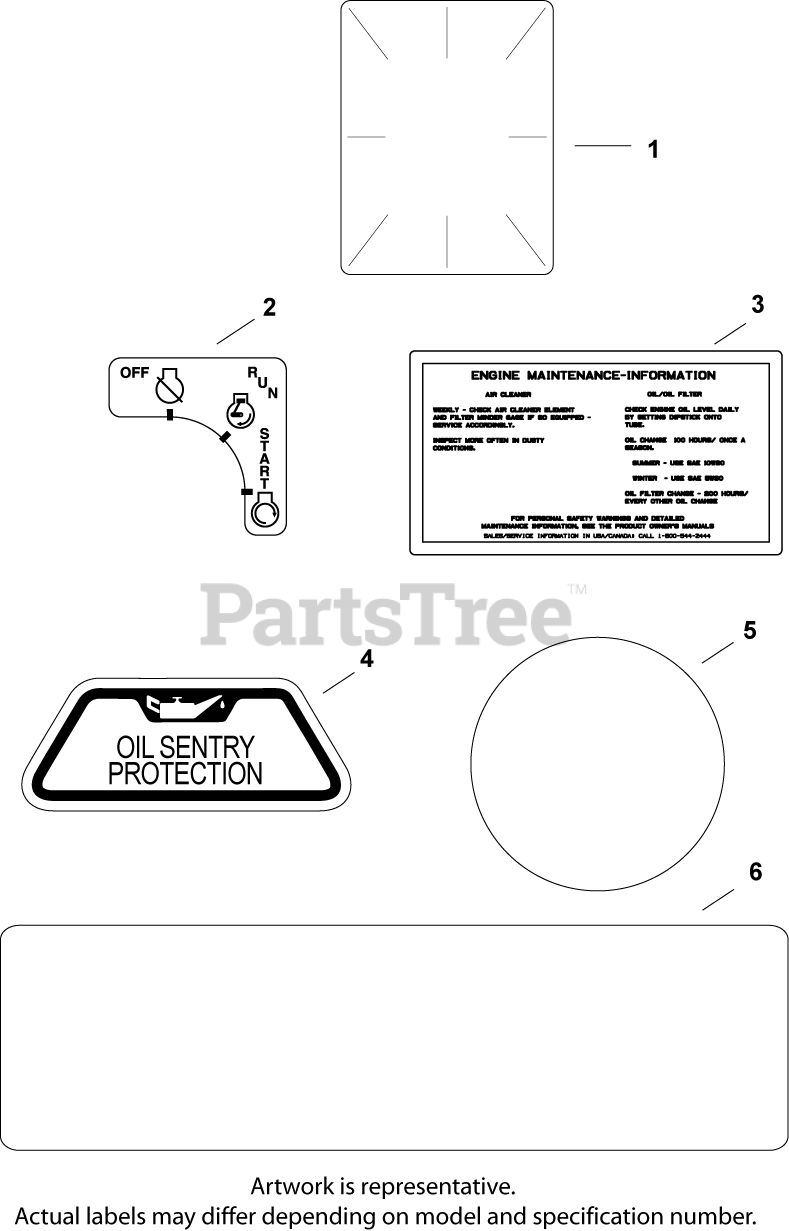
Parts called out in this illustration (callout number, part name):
1	DECAL, CLEAR LAMINATE USE 25 113 70-S
2	DECAL, KEY SWITCH
3	DECAL, AIR CLEANER - (#DSC)
4	DECAL, OIL SENTRY - (#DSC)
5	LABEL, (ROUND KOHLER GOLD)-USE 24 113 18
6	DECAL, 20 HP
